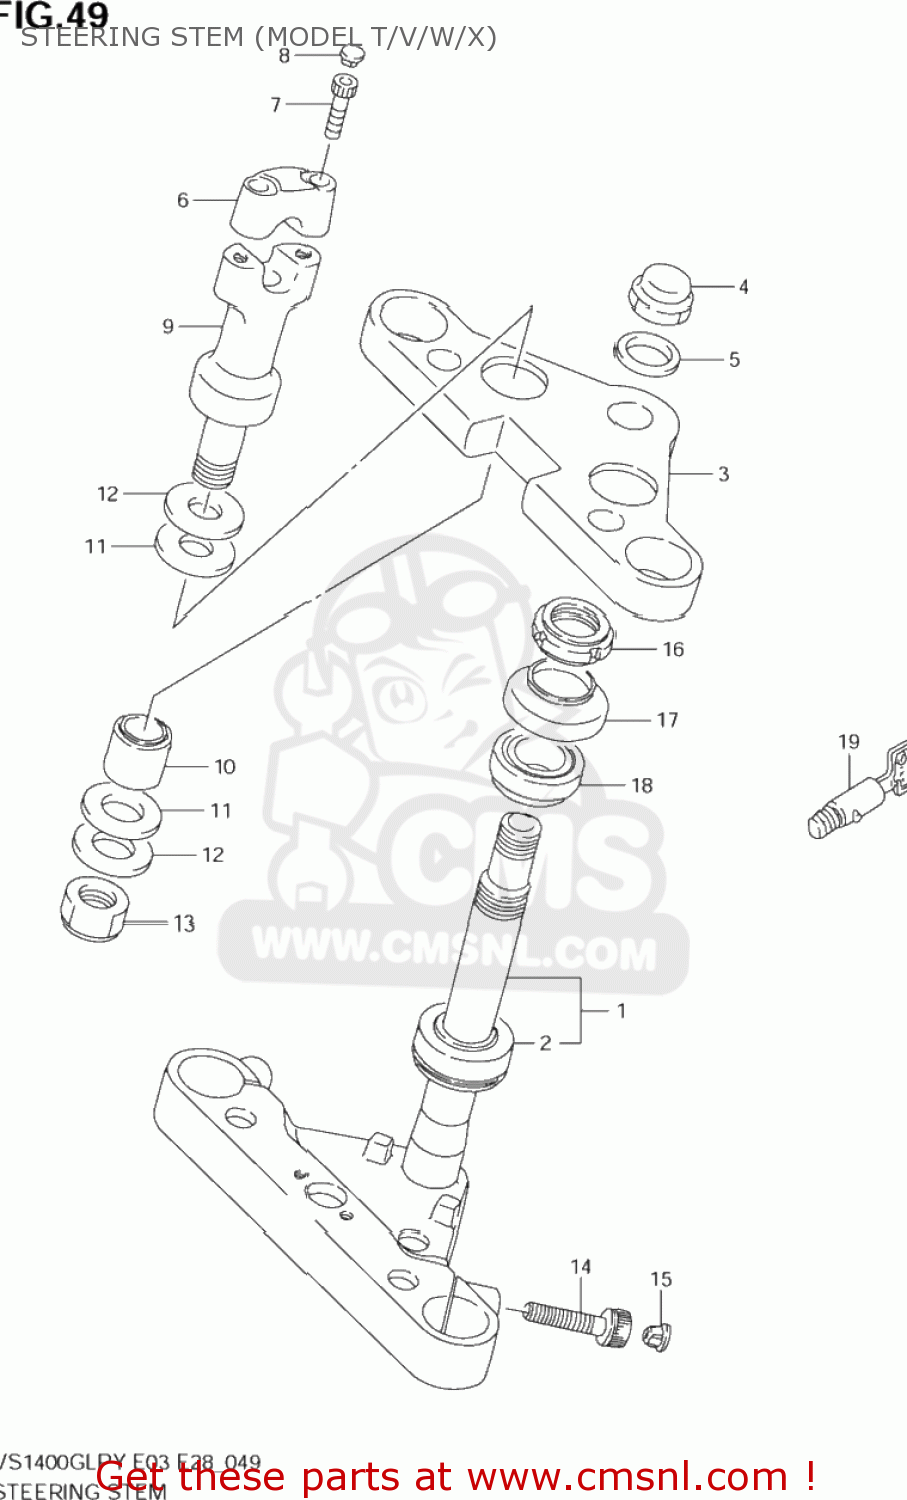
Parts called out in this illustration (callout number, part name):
1	STEM,STEERING
2	BEARING(30X55X17)
3	HEAD,STEERING STEM
4	NUT,CAP
5	WASHER(22.5X32X1.6)
6	HOLDER,HANDLE UPR
7	BOLT
8	CAP(OD:14.5)
9	HOLDER,HANDLE
10	CUSHION
11	SEAT,RUBBER
12	WASHER
13	NUT
14	BOLT
15	CAP(OD:12)
16	NUT,STEERING STEM(25X44X10)
17	SEAL,STEERING UPR DUST
18	BEARING(25X47X15)
19	LOCK SET,STEERING
